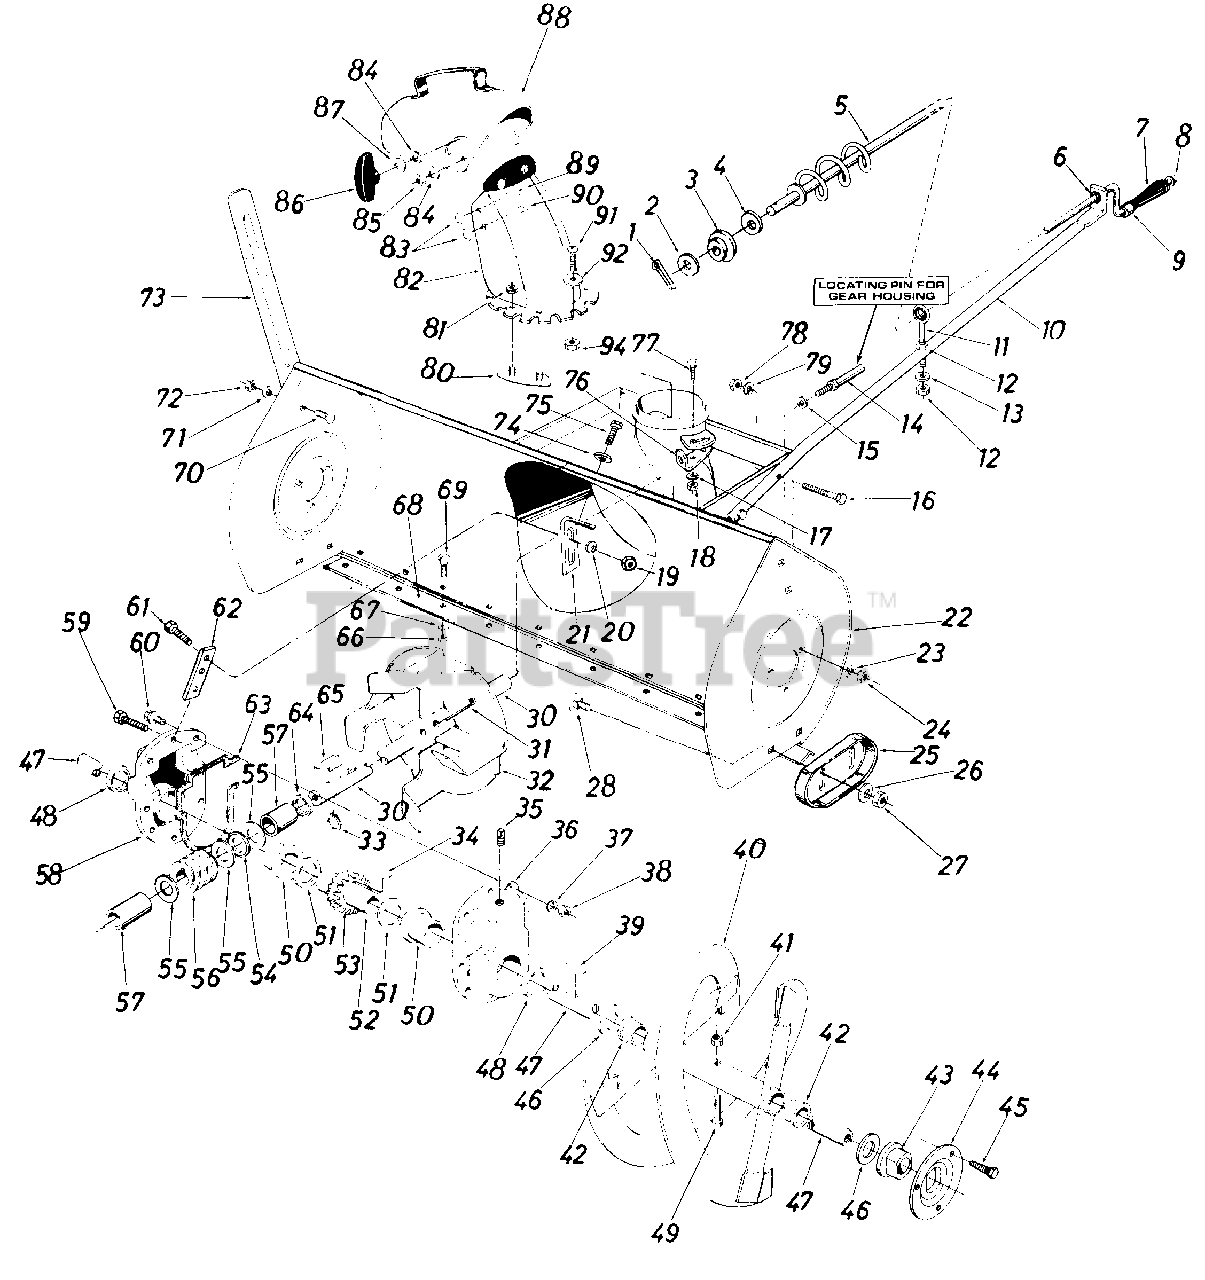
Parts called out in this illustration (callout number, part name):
1	Cotter Pin
2	Fl.-Wash. .39" I.D. x .62" O.D.
3	Plastic Bushing
4	Fl.-Wash. .385 I.D. x .62" O.D.
5	Chute Crank Ass'y.
6	Plastic Bushing
7	Knob Ball 3/8 Dia. Hole
8	Push Nut 3/8" Rod
9	Spacer .385 I.D. x .50" I.D.
10	Chute Crank Support Tubing
11	Eyebolt
12	Hex Nut 5/16-18 Thd.
13	Bell.-Wash. .345" I.D. x .88" 0. D.
14	Stud 3/8-16 x 2.75" Lg.
15	Bell.-Wash. .400" I.D. x .88" 0. D.
16	Hex Bolt 3/8-24 x 1.25" Lg.
17	Bell.-Wash. .345" I.D. x .88" 0. D.
18	Hex Nut 5/16-18 Thd.
19	Hex Nut 1/4-28 Thd.
20	Bell.-Wash. .265" I.D. x .75" 0. D.
22	45" Snow Blower Housing Ass'y
23	L.-Wash. 5/16" I.D.
24	Hex Nut 5/16-18 Thd.
25	Slide Shoe
26	Bell.-Wash. .400" I.D. x .88" 0. D.
27	Hex Jam Nut 3/8-16 Thd.
28	Carriage Bolt 3/8-16x .62" Lg.
30	Blower Axle .875" Dia. x 14.75" Lg.
31	Spring Pin Spir. 5/16" Dia. x 1.75" Lg.
34	#91 Woodr-Key 1/4 x 3/4" Dia. (HDN)
35	Vent Plug
36	Comp. Gear Hsg. Half-L.H.
37	Spr.-Wash . .32" I.D. x .62" O.D.
38	Hex Ins. L.-Nut 5/16-18 Thd.
39	#91 Woodr-Key 1/4 x 3/4" Dia. (HDN)
41	Hex Ins. L.-Nut 5/16-18 Thd.
42	Plastic Bushing
43	Flange Brg. w/flats 1" I.D.
44	Bearing Housing
45	Hex Sems Bolt 5/16-18 x .75" Lg.
46	Fl.-Wash. 1.00" I.D. x 1.75" O.DI.
47	Spiral Axle
48	Flange Bearing 1.503" I.D.
49	Shear Bolt 5/16-18 x 1.75" Lg.
50	Oil Seal 1.50" I.D.
51	Fl.-Wash. 1.50" I.D. x 2.00" O.D.
52	Worm Gear Shaft
53	Double Threaded Worm Gear-O.D.
54	Thrust Brg.-.88" I.D. x 1.44" 0.D.
55	Fl.-Wash. .88" I.D. x 1.4" 0.D.
56	Double Threaded Worm-L.H.
57	Sleeve
58	Complete Gear Hsg. Half-R.H.
59	Hex Bolt5/16-18x 1.25" Lg.
60	Hex Bolt 5/16-18 x 1.0" Lg. (Grade 5)
61	Hex Bolt 1/4-28 x .75" Lg.
62	Gear Housing Support Plate
63	Rubber Gasket
64	Oil Seal-.875" I.D.
65	#9 Hi-Pro Key 3/16 x 3/4" Dia. (HT.)
66	Hex Nut 5/16-18 Thd.
67	L.-Wash. 5/16" I.D.
69	Carriage Bolt 5/16-18 x 1.00" Lg.
70	Carrlage Bolt 5/16-18 x .62" Lg.
71	L.-Wash.5/16" I.D.
72	Hex Nut 5/16-18 Thd.
73	Guide Blade
74	Bell.-Wash. .345" I.D. x .88" O.D.
75	Hex Wash. Hd. AB Tap Scr. 5/16 x .75" Lg.
77	Carriage Bolt 5/16-18 x .75" Lg.
78	Hex Ins. L.-Nut 3/8-24 Thd.
79	L.-Wash. 3/8" I.D.
80	Chute Flange Keeper
81	Hex Cent. L.-Nut 1/4-20 Thd.
82	Chute Ass'y. w/Chute Guard
83	Fl.-Wash. .285" I.D. x 1.25" O.D.
84	Bell.-Wash. .345" I.D. x .88" O. D.
85	HexCent. L.-Nut 5/16-18 Thd.
86	Knob Handle
87	Bell.-Wash. .345" I.D. x .88" O.D.
88	Top Chute Ass'y.
89	Carriage Bolt 5/16-18 x 1.00" Lg.
90	Carriage Bolt 5/16-18 x .62" Lg
91	Truss Mach. Scr. 1/4-20 x .50"
92	Fl.-Wash. .285" I.D. x 1.25" O.D.
94	Hex Cent. L-Nut-1/4-20 Thd.
